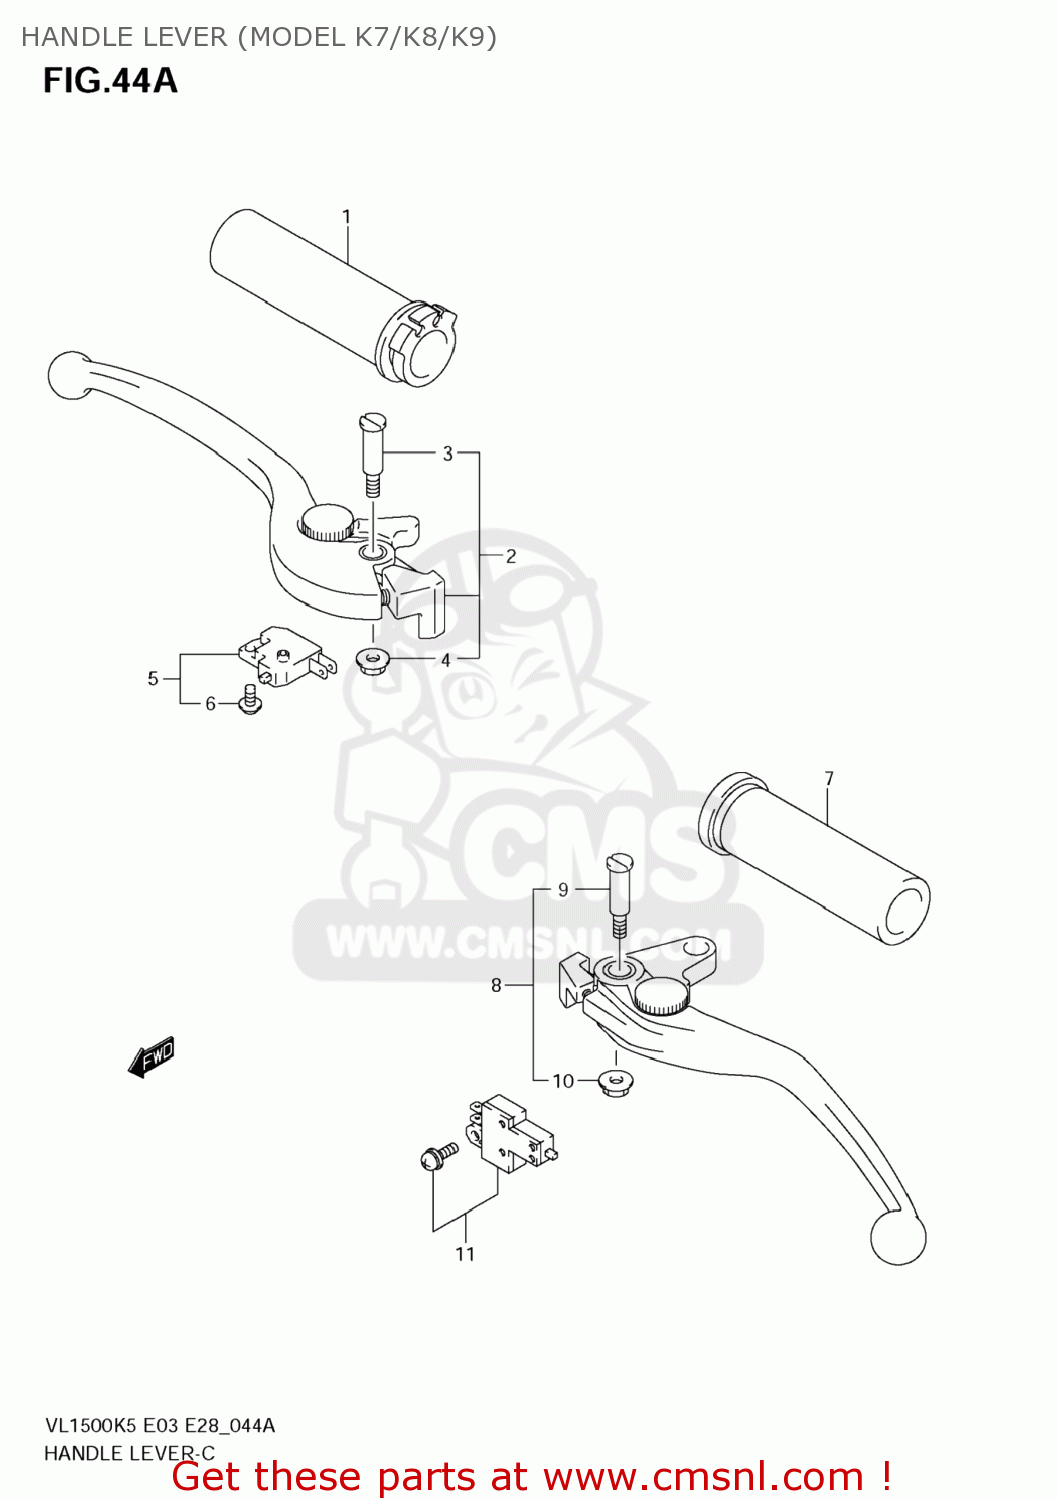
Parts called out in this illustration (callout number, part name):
1	GRIP,THROTTLE
2	LEVER ASSY,BRAKE
3	BOLT,PIVOT
4	NUT
5	SWITCH ASSY,ST
6	SCREW
7	GRIP,L
8	LEVER ASSY,CLUTCH
9	BOLT,PIVOT
10	NUT
11	SWITCH ASSY,CLUTCH
